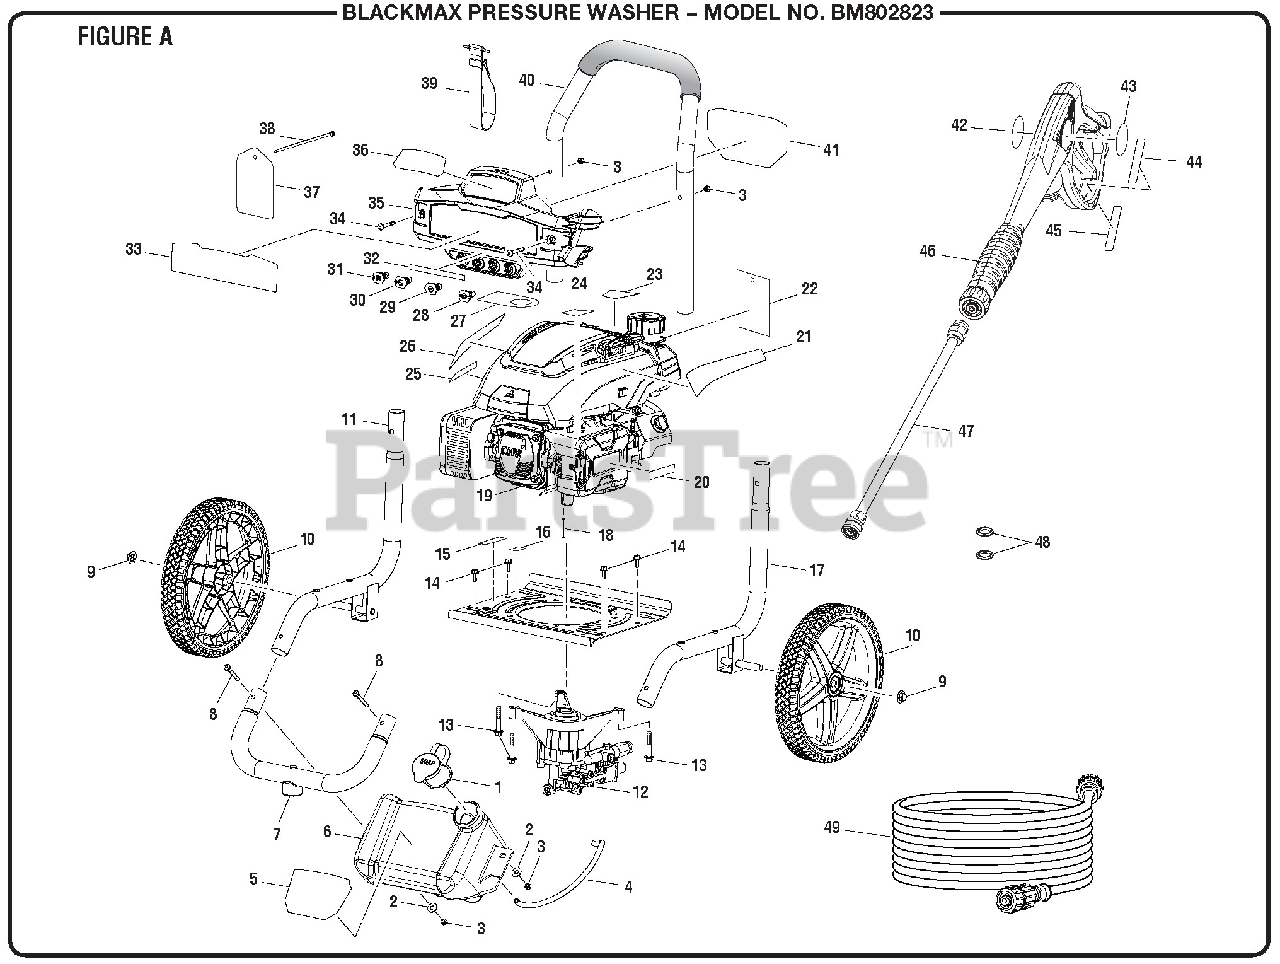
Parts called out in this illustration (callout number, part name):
1	Soap Tank Cap
2	Washer (1/4 in.)
3	Lock Nut (M6)
4	Chemical Siphon Tube
5	Soap Tank Label
6	Soap Tank
7	Main Frame Assembly (Front)
8	Bolt (M6 X 48 mm, T30 Torx Hd.)
11	Main Frame Assembly (Left)
12	Pump (See Figure B)
13	Bolt (M8 x 45 mm, Flange Hd.)
14	Bolt (M6 x 16 mm, Flange Hd.)
15	Combustion Warning Label
16	Add Oil Label
17	Main Frame Assembly (Right)
18	Output Shaft Key
19	Engine (Mitsubishi 173 cc, Recoil Start)
20	Inquiries Label
21	Left Wing Label
22	Danger Hangtag
23	E85 Label
24	Choke Label
25	Hot Surface Label
26	Right Wing Label
27	Oil Dipstick Hangtag
28	Soap Nozzle
29	40° Nozzle
30	25° Nozzle
31	15° Nozzle
32	Nozzle Callout Label
33	Performance Label (Mitsubishi)
34	Bolt (M6 x 42 mm, T30 Torx Pan Hd.)
35	Hose and Nozzle Holder Assembly
36	Logo Label
37	Nozzle Hangtag
39	Hose Holder Strap
40	Handle Assembly
41	Quick Start Label
42	Trigger Handle Warning Label (English)
43	Blackmax Spray Wand Logo Label
44	Trigger Handle Warning Label (French/Spanish)
45	Trigger Handle Rating Label
46	Trigger Handle Assembly
47	Spray Wand
48	O-Ring Kit
49	Hose (25 ft.)
